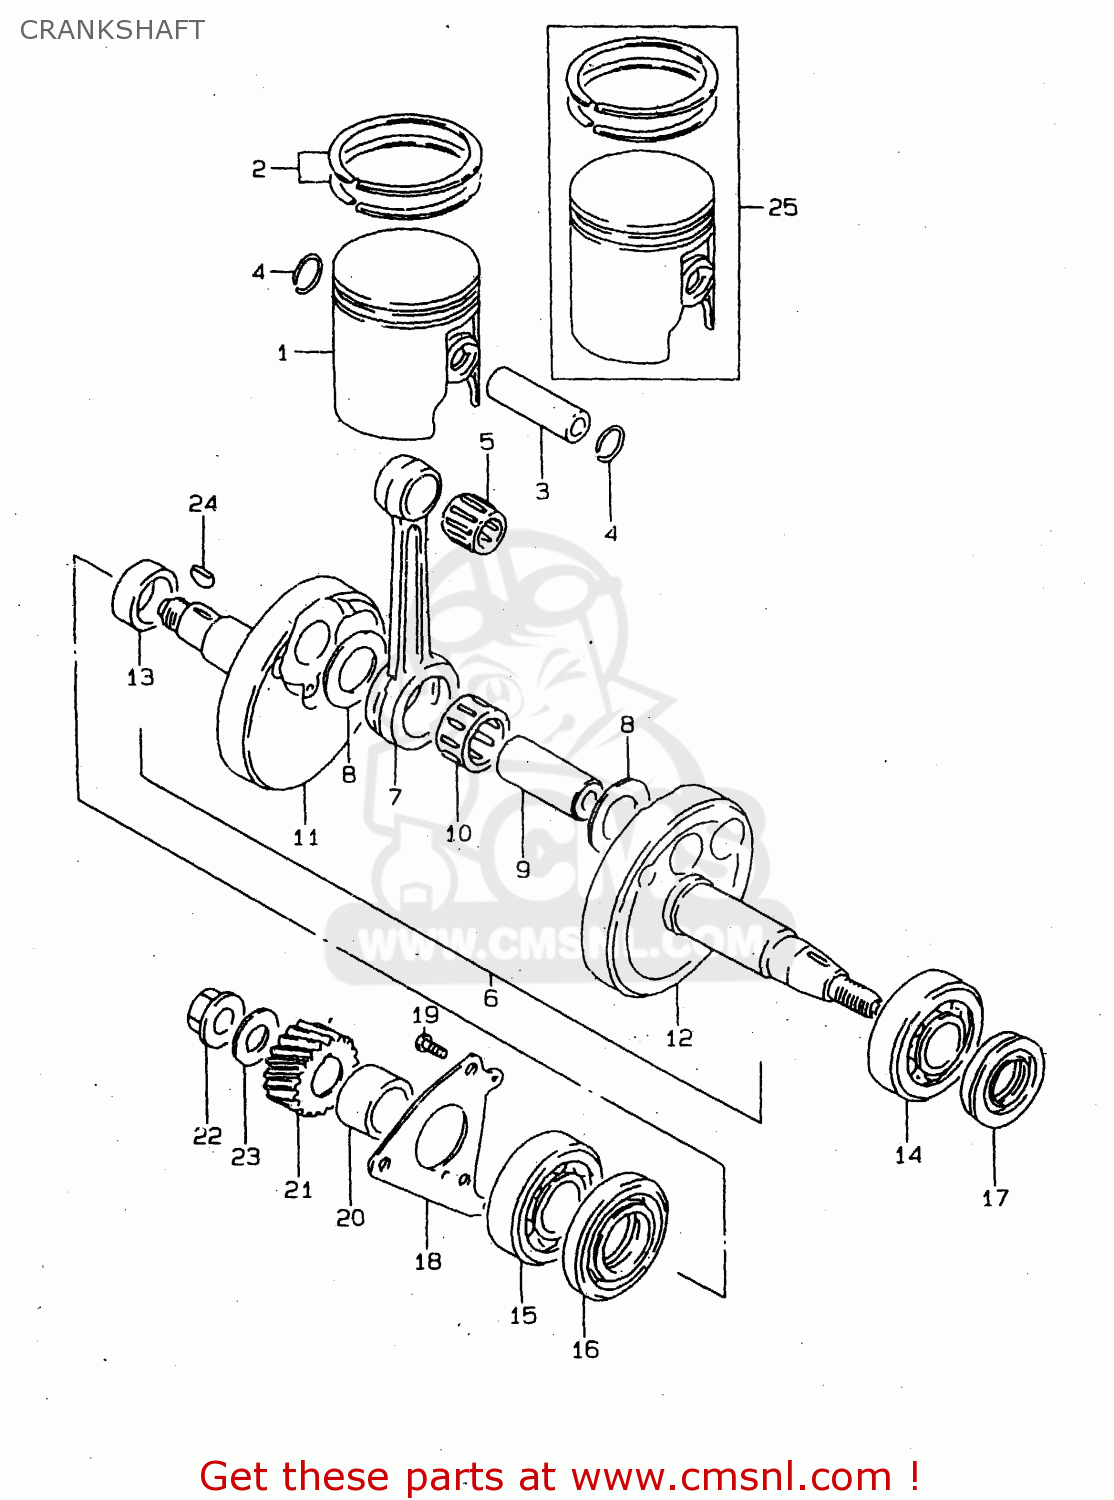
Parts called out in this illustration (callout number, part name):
1	PISTON (49.00MM)
2	PISTON RING SET STD
3	PIN,PISTON
4	RING,SNAP
5	BEARING(12X16X16)
6	CRANKSHAFT ASSY
7	ROD,CONNECTING
8	WASHER(17X29X1)
9	PIN,CRANK
10	BEARING(17X23X14)
11	CRANKSHAFT,R
12	CRANKSHAFT,L
13	SPACER(20X26X9)
14	BEARING
15	BEARING(20X47X14)
16	SEAL,OIL(26X47X7.3)
17	SEAL,OIL(19.6X37X8)
18	RETAINER,CRANKSHAFT BEARING,R
19	SCREW
20	SPACER(20X26X14)
21	GEAR,PRIMARY DRIVE NO.19
22	NUT
23	WASHER
24	KEY
25	PISTON SET (OS:0.5)
